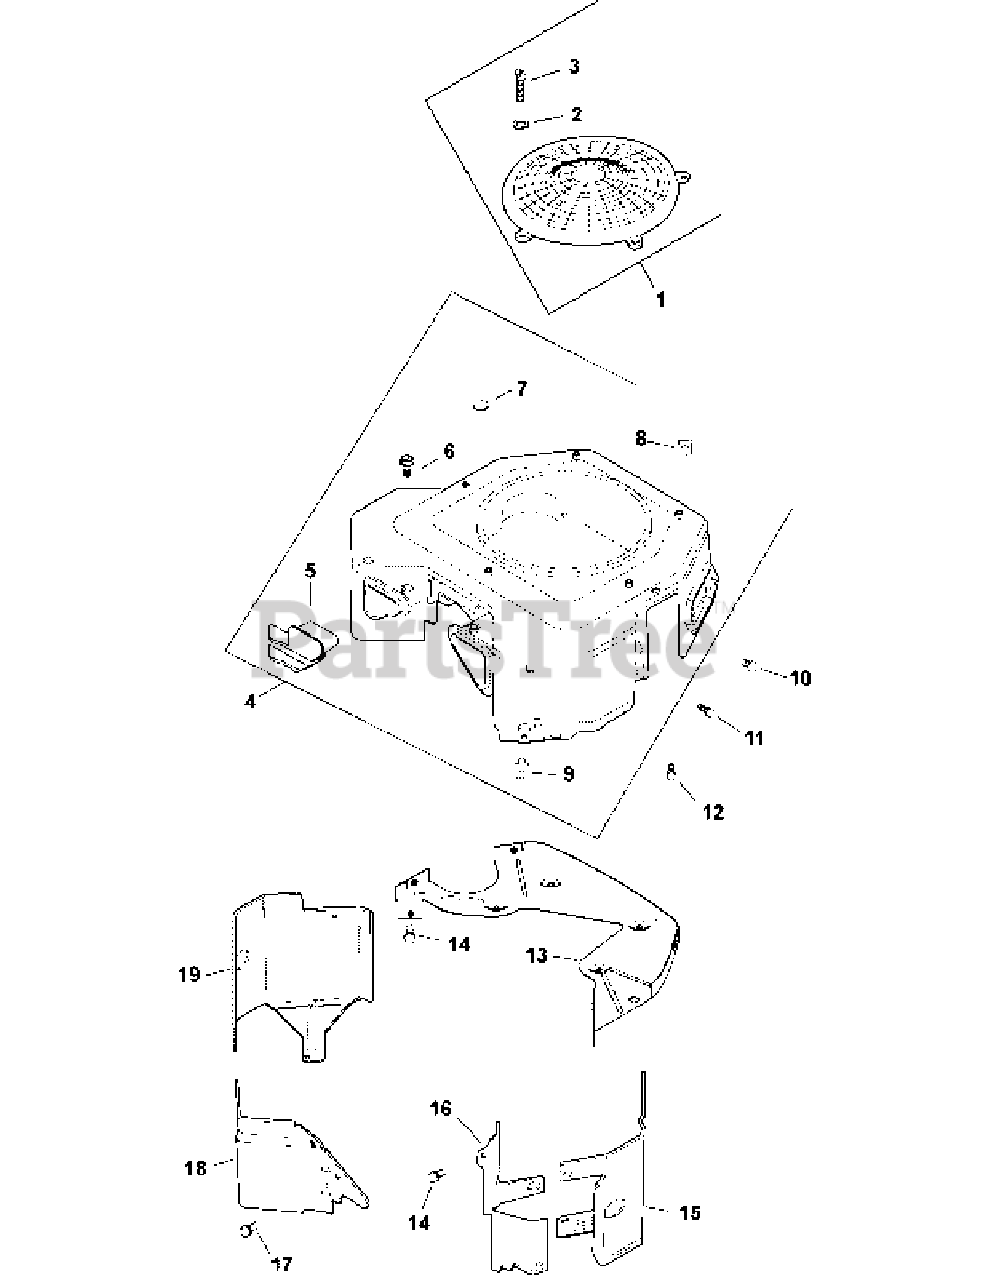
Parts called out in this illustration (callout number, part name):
1	KIT, FIXED GUARD
2	WASHER, FLAT 7/32"
3	SCREW, LBD SCKT PAN M5X0.8X10
4	KIT, BLOWER HOUSING ASSEMBLY
5	COVER, BLOWER HOUSING
6	SCREW, WSH HD TAP #8-18X1/2"
7	PLUG, BUTTON 9/16
9	NUT, PLASTIC - USE 25 100 37-S
10	SCREW, FLG THD FRM M5X.8X16
11	SCREW, FLG THD FRM M5X.8X16
12	SCREW, FLG THD FRM M5X.8X20
13	KIT, BACKING PLATE - USE 24 146 55-S
14	SCREW, FLG THD FRM M6X1.0X16
16	BAFFLE, VALLEY #2 SIDE
17	SCREW, FLG THD FRM M5X.8X10
18	BAFFLE, VALLEY #1SIDE
